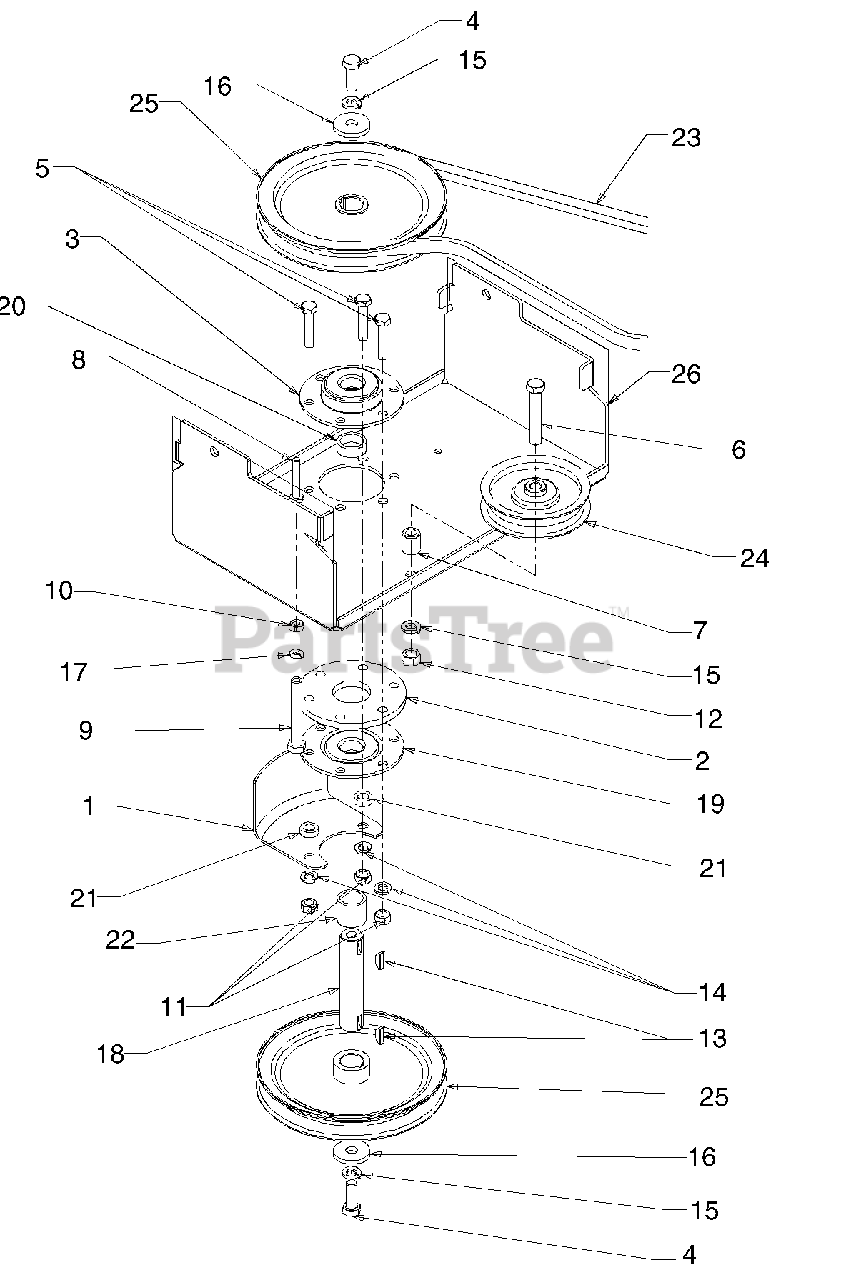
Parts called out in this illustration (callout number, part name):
3	OPEN BRG. HOUSING 1.85
4	HHCS:3/8-24:1.00:GR5:LOCK
5	HHCS:5/16-24:1.50:GR5:STD
6	HHCS:3/8-16:2.25:GR2:STD
7	SPCR:.385 X .623 X .750 LG
8	PIN:GDE:.250 DIA X 1.68 LG
9	PIN:CLEVIS:.375 DIA X 2.63 LG
10	NUT:LOCK:1/4-20
11	NUT:5/16-24:GRA:HX
12	NUT:3/8-16:GRA:HX
13	KEY:HI-PRO 3/16 X 5/8
14	WASH:LOCK:5/16:REGULAR DUTY
15	WASH:LOCK:3/8:REGULAR DUTY
16	FLAT WASHER .406 ID X 1 1/4 OD
17	WASH:LOCK:1/4:REGULAR DUTY
18	SHAFT- .787 DIA X 3.81 LG.
19	HSG ASM:BEARING
20	SPACER .790 ID X .347 LG.
21	SPACER .378 ID X .625 OD X .22
22	SPACER-.80 ID X 1.00 OD X .900
23	BELT: V: 1/2 X 52.00 LG
24	FL-IDLER W/ FLANGES 3.75 OD
25	PUL:V TYP:6.50 OD
